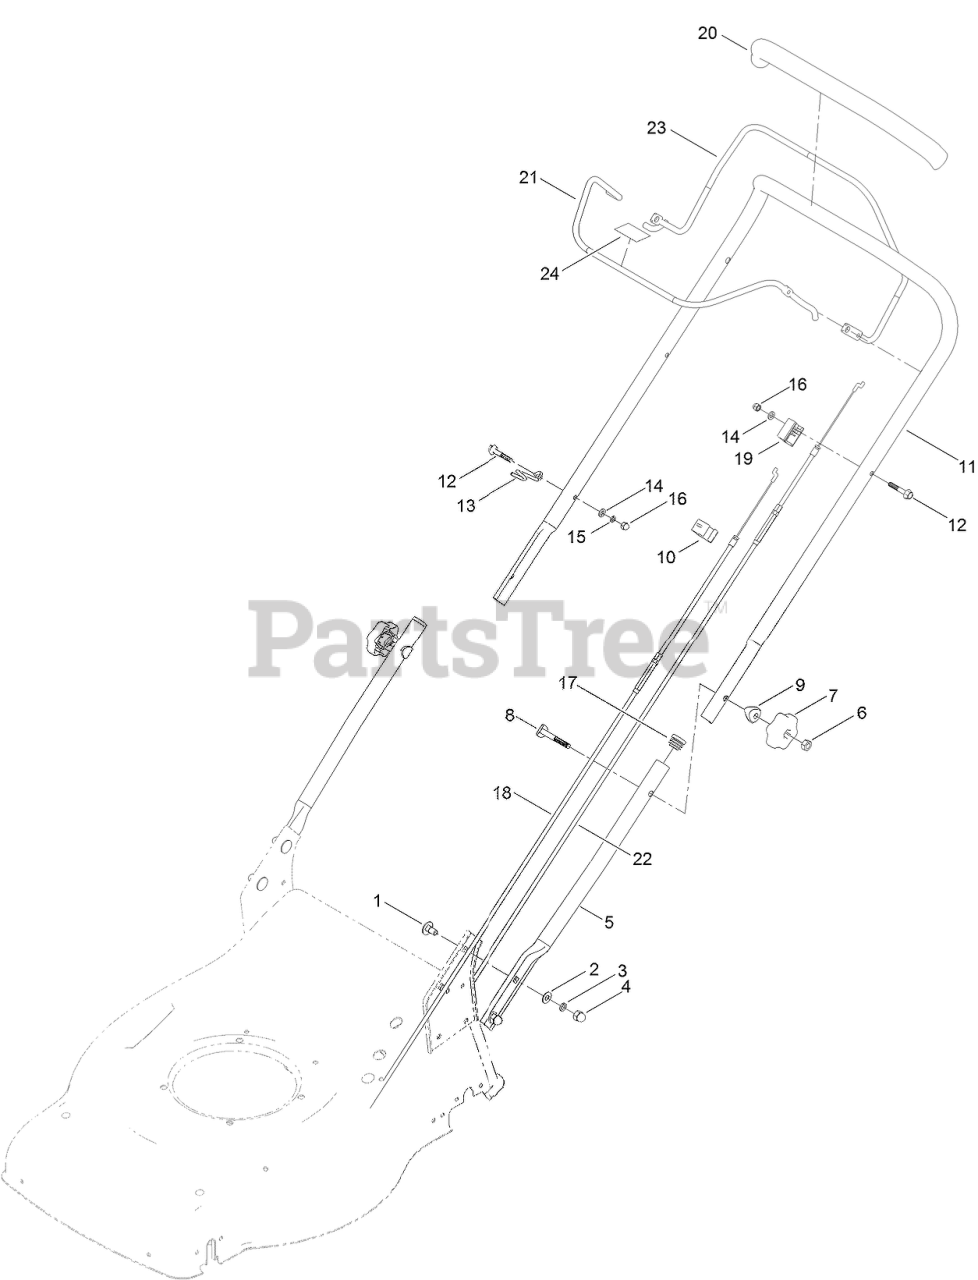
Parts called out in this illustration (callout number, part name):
2	WASHER
3	WASHER-SPRING
4	NUT-LID
5	HANDLEBAR-LOWER
6	NUT-HEX
7	KNOB-ROTARY
8	BOLT-FLAT HEAD
9	WASHER-CURVE
10	CABLE CLAMP
11	HANDLEBAR-UPPER
12	BOLT-HH, FLANGE
13	HOOK-CABLE
14	WASHER-PLAIN
15	WASHER-SPRING
16	NUT-LID
17	PLUG-TUBE
18	CABLE-BRAKE, ENGINE
19	CABLE-BLOCK, FIXED
20	GRIP-HANDLE
21	LEVER-ENGINE
22	CABLE-CLUTCH
23	LEVER-CLUTCH, GEARBOX
24	DECAL-STOP
